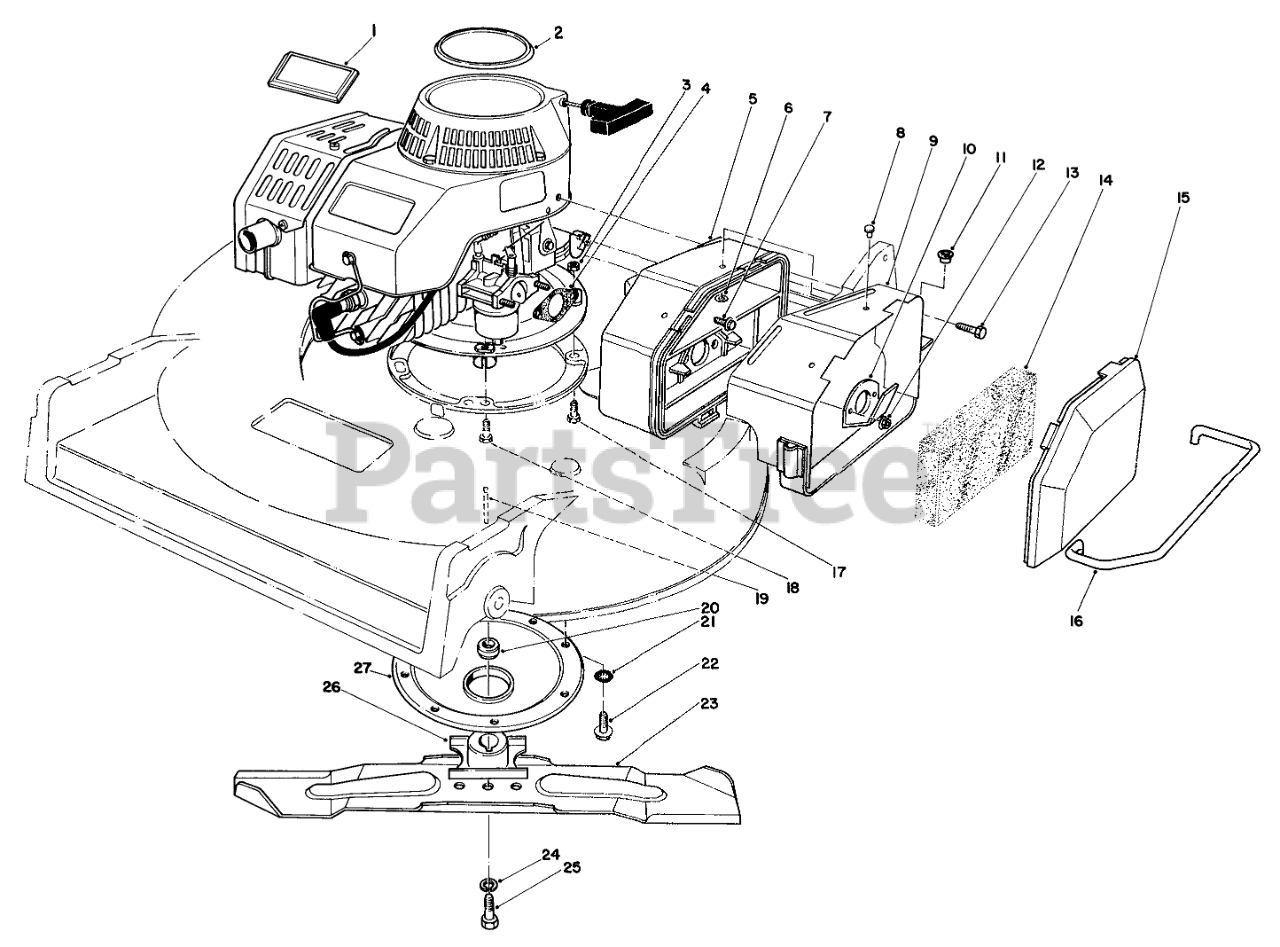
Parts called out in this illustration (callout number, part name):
1	Plate-Logo
2	Plate-Engine Logo
3	NUT-JAM
4	GASKET-AIR CLEANER
5	Air Cleaner Assembly (Incl. Ref. #6, 8 & 9
6	WASHER-FLAT
7	HEX FL HD M.6X1.0X25MM
8	NUT-HEX
9	AIR CLEANER COVER WA
10	SPIT BACK DEFLECTOR
11	5/16 ID BSHG
12	NUT-LOCK
13	SCREW-HHF
14	FILTER
15	AIR CLEANER COVER
16	AIR CLEANER GUARD
17	SCREW-HH
18	SCREW-HH
19	KEY-SQUARE
20	SPACER-BLADE RETAINER
21	WASHER-LOCK, INTERNAL
22	SCREW-HWHTF
23	BLADE-21in
24	WASHER-LOCK
25	SCREW-BLADE
26	RETAINER-BLADE
27	PROTECTOR-CRANKSHAFT
